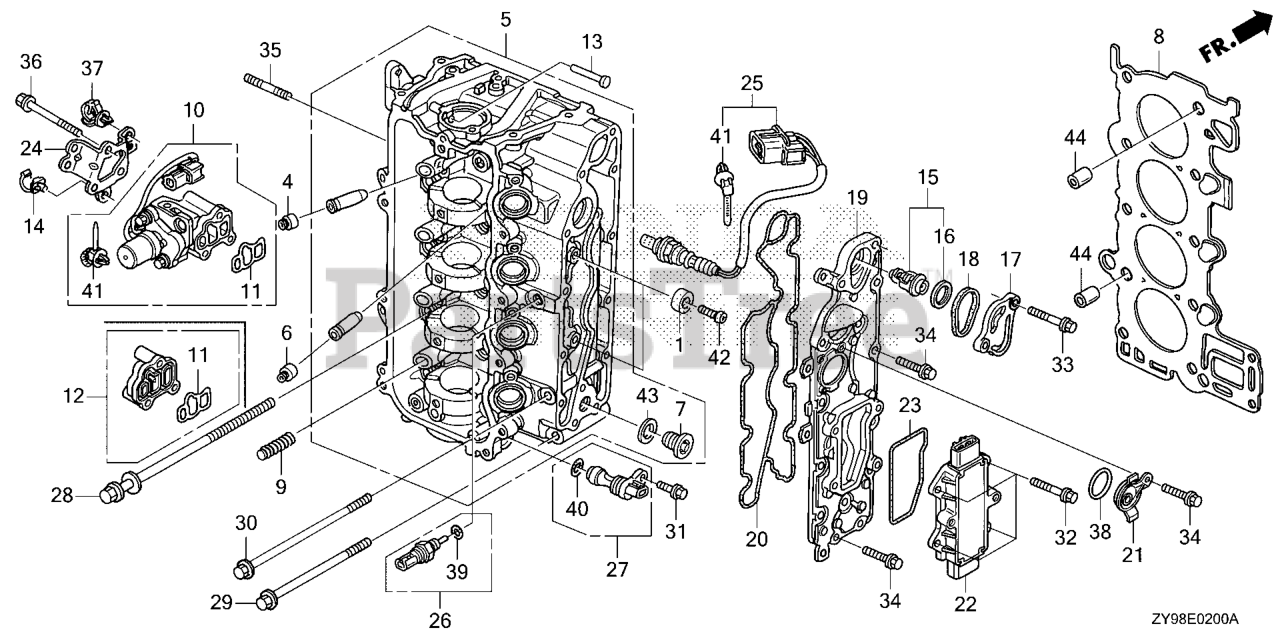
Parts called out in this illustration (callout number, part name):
1	METAL, ANODE
2	GUIDE, VALVE (OVER SIZE)
3	GUIDE, EX. VALVE (OVER SIZE)
4	SEAL A, VALVE STEM (NOK)
5	CYLINDER HEAD *NH8* (DARK GRAY)
5	HEAD COMP *NH8*
6	SEAL B, VALVE STEM (NOK)
7	BOLT, SEALING (20MM)
8	GASKET, CYLINDER HEAD
9	MOTION, LOST
10	VALVE ASSY., SPOOL *NH8* (DARK GRAY)
11	FILTER ASSY., SPOOL VALVE
13	LIFTER, FUEL PUMP
14	CLAMP B, FUEL TUBE
15	THERMOSTAT ASSY.
16	RUBBER, RING
17	COVER, THERMOSTAT
17	COVER THERMOSTAT
18	O-RING, THERMOSTAT COVER
19	COVER, WATER JACKET (NOT AVAILABLE)
19	COVER, WATER JACKET
20	GASKET, EX. WATER JACKET COVER
21	COVER, ANODE
22	RECTIFIER ASSY., REGULATOR
23	GASKET, REGULATOR
24	BRACKET, HARN CLIP D
25	SENSOR, OXYGEN
26	SENSOR ASSY., WATER TEMPERATURE
27	SENSOR ASSY., TDC
28	BOLT-WASHER (9X155)
29	BOLT, FLANGE (8X95)
30	BOLT, FLANGE (8X110)
31	BOLT, FLANGE (6X16)
32	BOLT, FLANGE (6X20)
33	BOLT, FLANGE (6X35)
34	BOLT, FLANGE (6X22)
35	BOLT, STUD (8X32)
36	BOLT, FLANGE (6X55)
37	CLIP, HARNESS
38	O-RING (33X2.4)
39	O-RING (9.5X1.9)
40	O-RING (15X1.9)
41	CLIP, HARNESS BAND (145MM) (BLACK)
42	BOLT, FLANGE (6X18)
42	SCREW, PAN (6X18)
43	WASHER, DRAIN PLUG (20MM)
44	PIN A, DOWEL (14X20)
